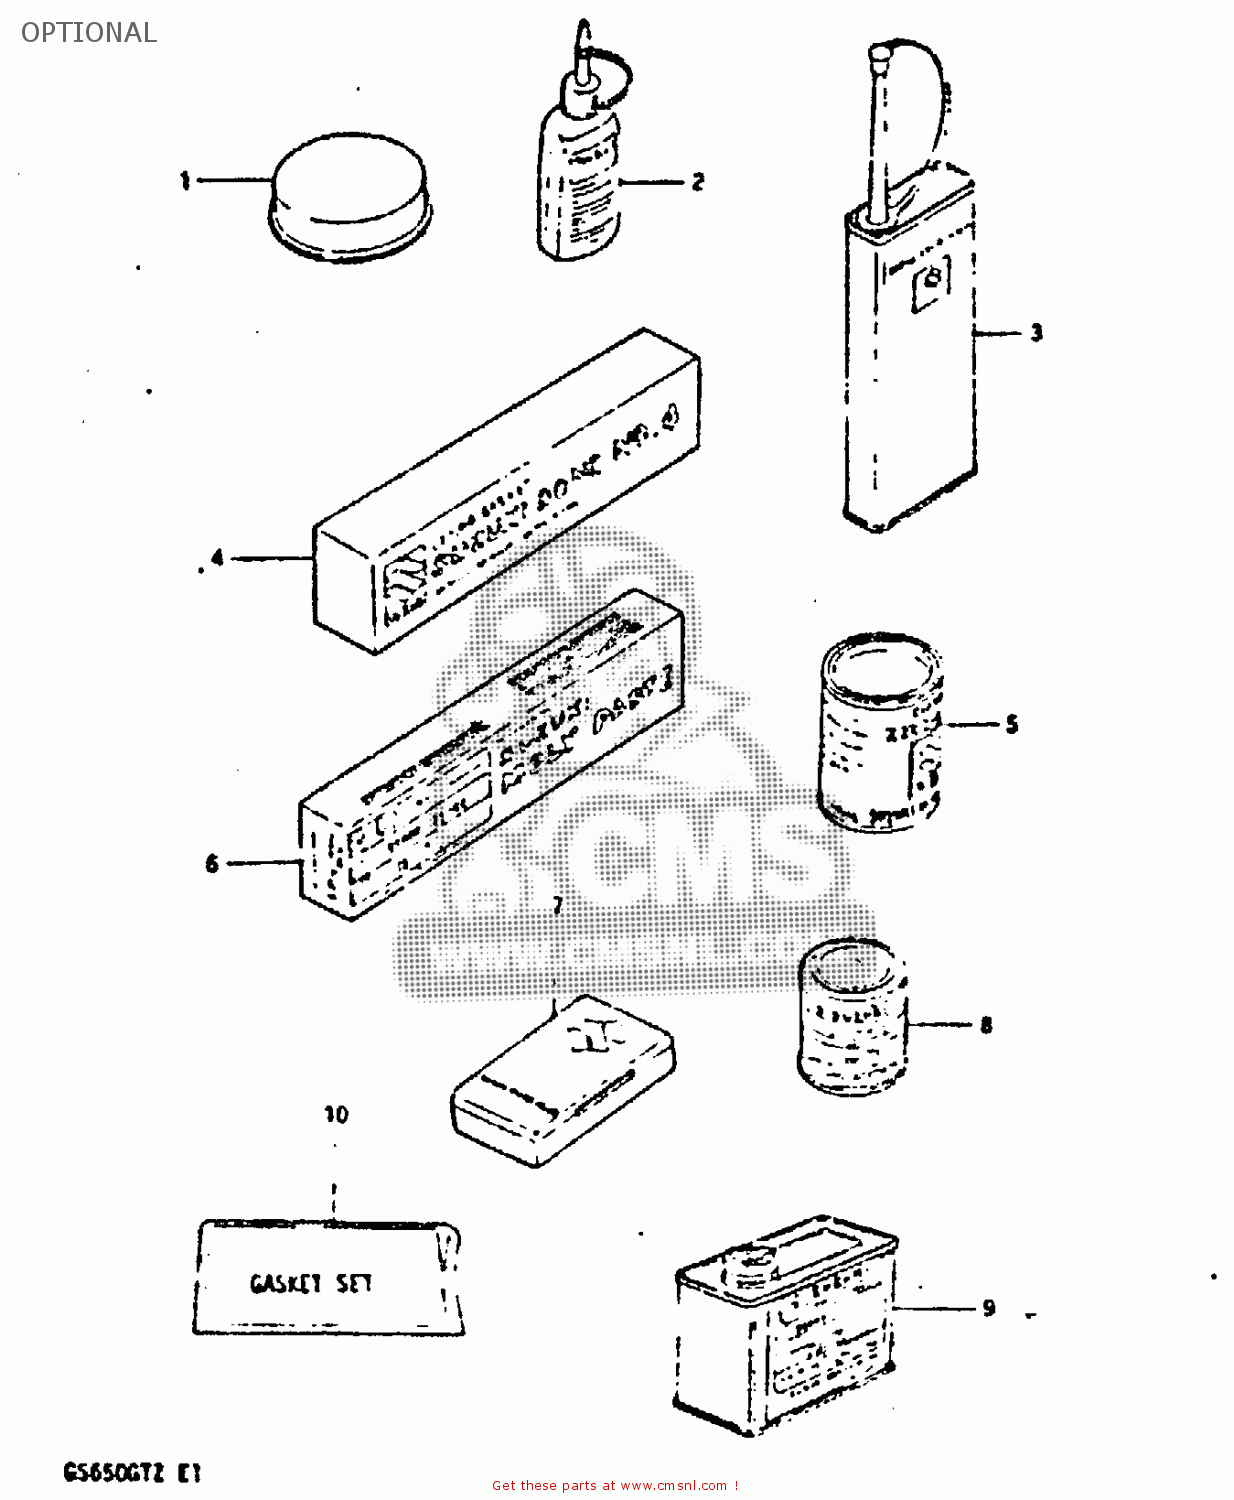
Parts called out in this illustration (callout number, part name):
1	GREASE,PBC FOR BRK PAD 20G
2	THREAD LOCK SUPER (1332B)
3	THREAD LOCK NO.1401 CLEAR 200G
4	BOND 1104
5	GREASE(C)EP2 LITHIUM 150G
6	SUZUKI MOLY PASTE
7	TUBE REPARING TOOL
8	PAINT,BLACK
9	PAINT (BLACK)
10	GASKET SET
